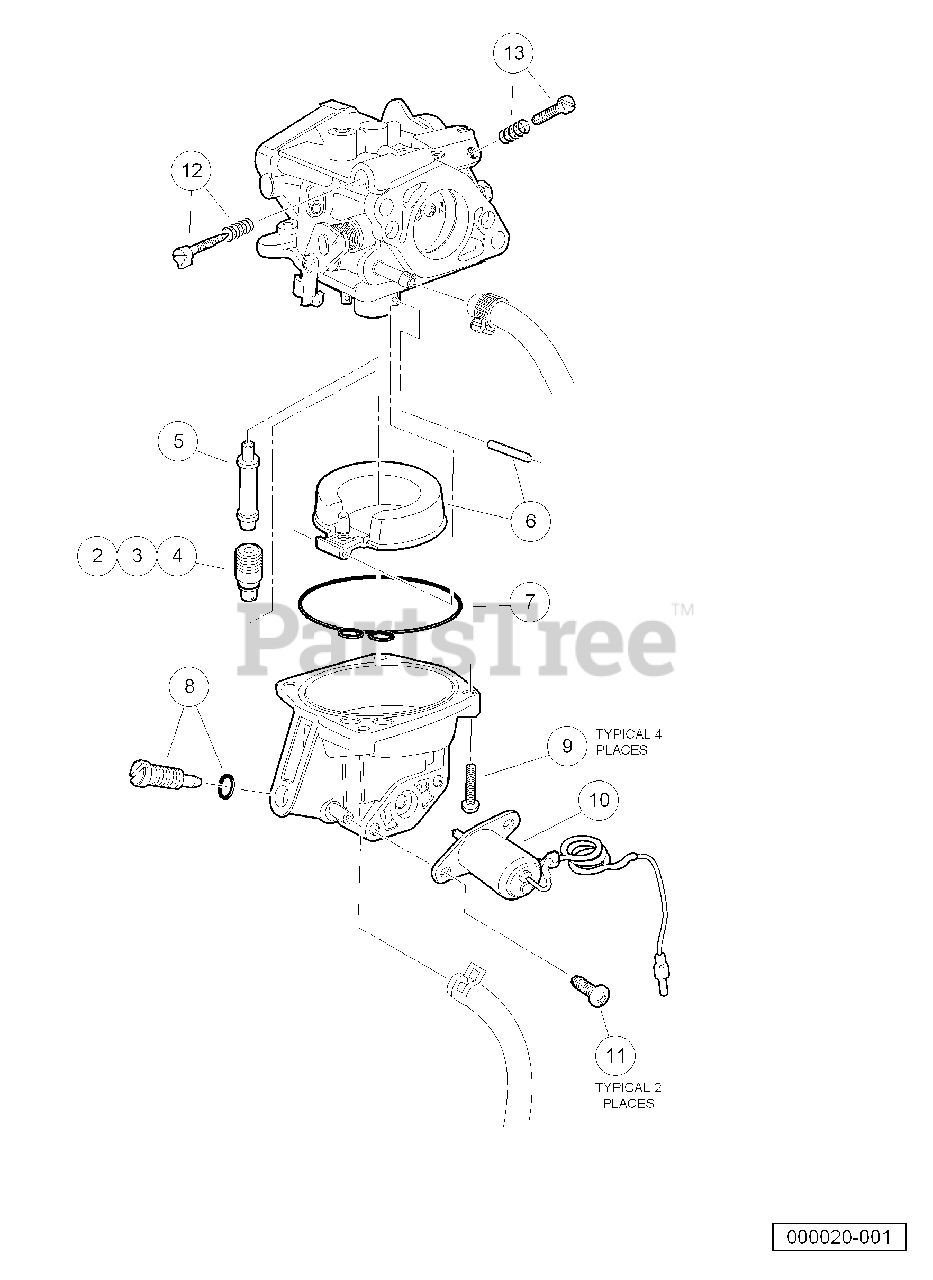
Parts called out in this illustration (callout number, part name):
1	Carburetor, Seal Shaft
2	Jet, GX620, #102
3	Jet, GX620, #105
4	Jet, GX620, #108
5	Nozzle, Main
7	Gasket Set
8	Screw Set, Drain
9	Screw-Washer, M4 X 14
10	Valve Assy., Solenoid
11	Screw-Washer, M5 X 12
12	Screw Set, Left
13	Screw Set, Right
